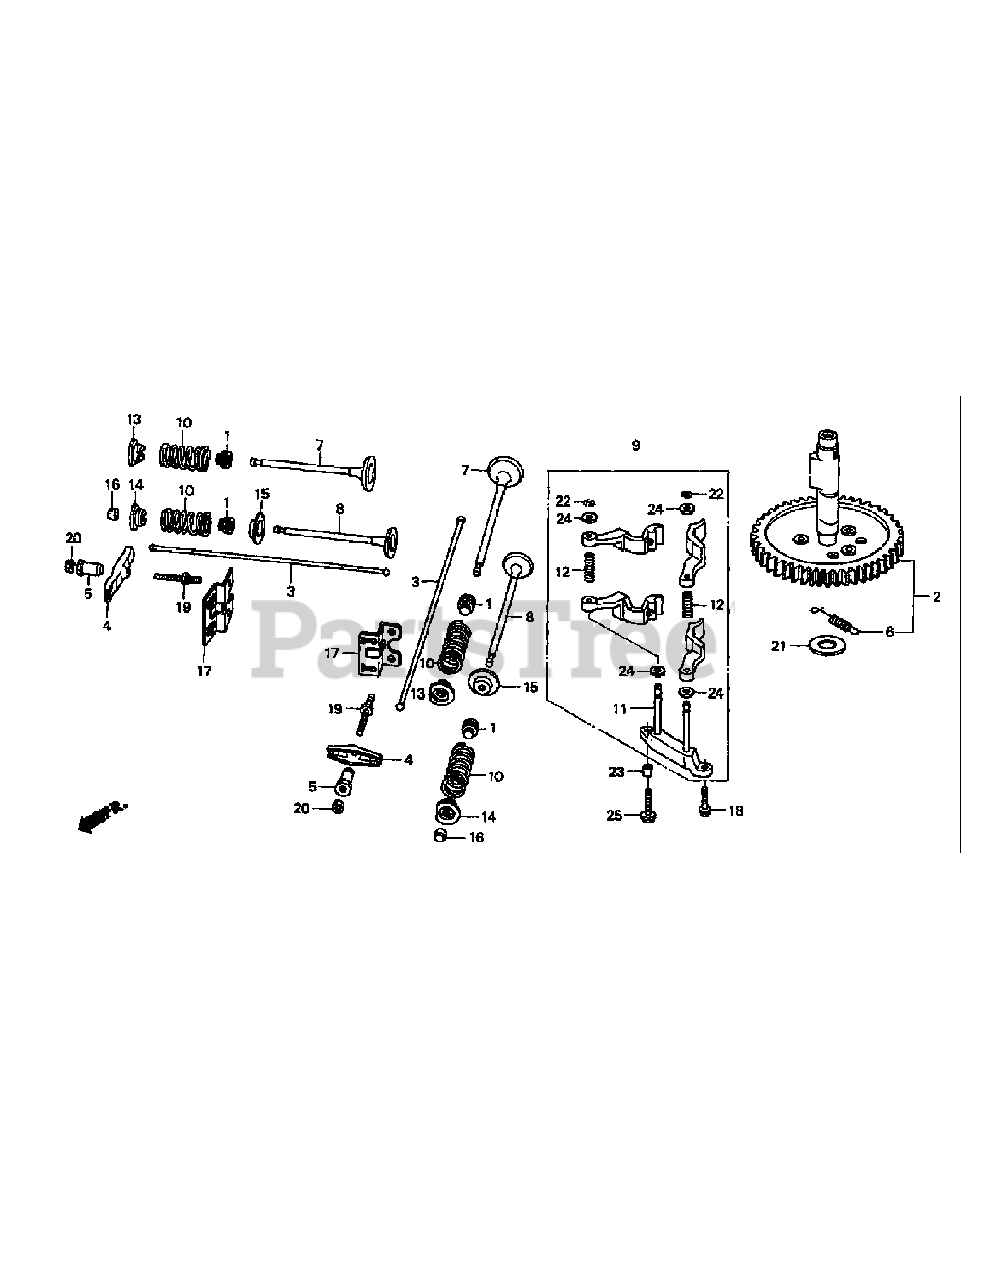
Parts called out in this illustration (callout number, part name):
1	Valve Stem Seal
2	Camshaft Assy.
4	Valve Rocker Arm
5	Rocker Arm Pivot
6	Weight Return Spring
7	Intake Valve
8	Exhaust Valve
9	Valve Lifter Assy.
10	Valve Spring
11	Valve Lifter Shaft
12	Valve Lifter Spring
13	Valve Spring Retainer (Intake)
14	Valve Spring Retainer (Exhaust)
15	Valve Spring Seat
16	Valve Rotator
17	Push Rod Guide
18	Flange Bolt (5x16)
19	Pivot Bolt (8mm)
20	Adjustable Pivot Nut
21	Thrust Washer (17.2mm)
22	Governor Holder Clip
23	Dowel Pin (8x12)
24	Plain Washer (6mm)
25	Flange Bolt (6x25)
